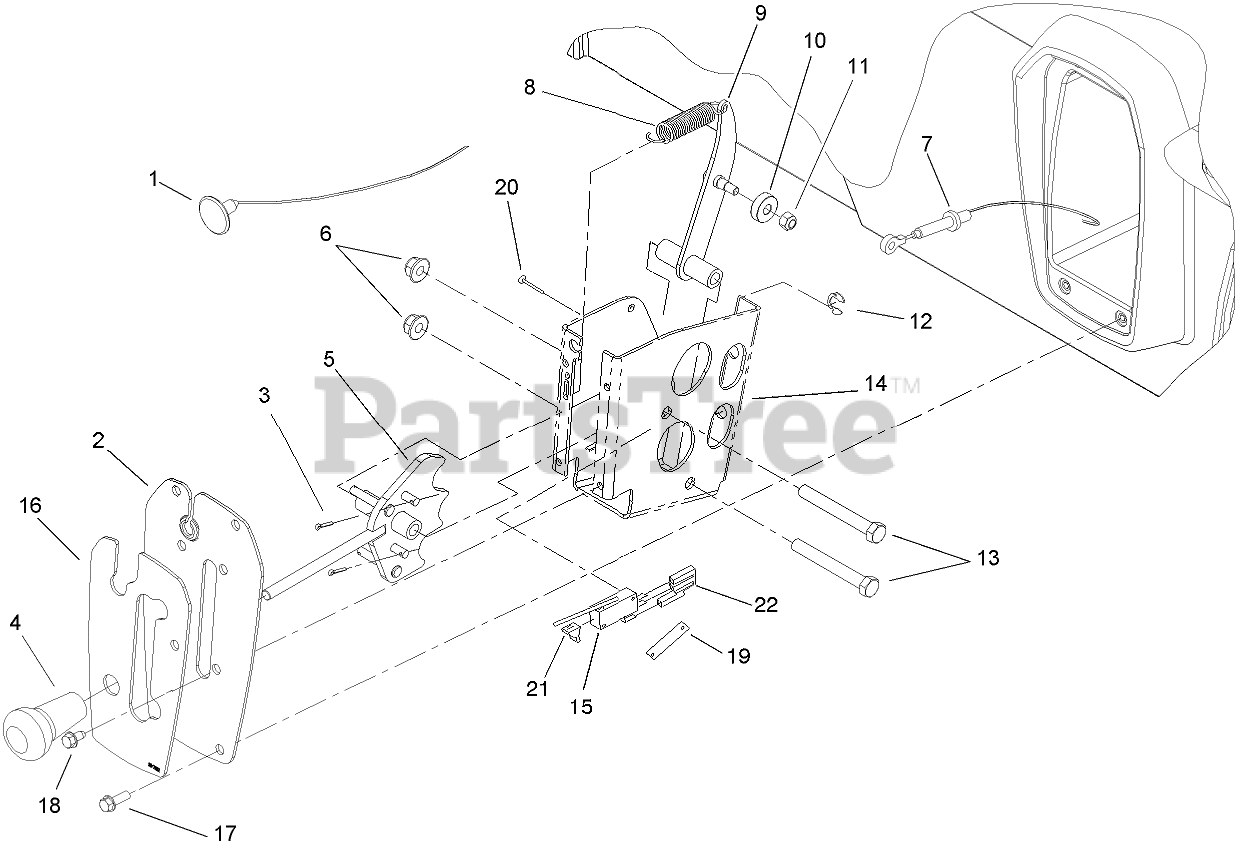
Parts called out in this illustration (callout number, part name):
1	CABLE-CHOKE
2	PLATE-SHIFTER
3	PIN-COTTER
4	KNOB-GRIP, SOFT
5	LEVER-SHIFT
6	NUT-HF, NI
7	Cable-Shift
8	SPRING-RETURN, PEDAL
9	ARM-DETENT
10	BEARING-BALL
11	NUT-LOCK, NI
13	SCREW-HH
14	BRACKET-SHIFT
15	SWITCH-MICRO
16	DECAL-SHIFTER
17	SCREW-HWH
18	SCREW
19	NUT-SPEED
20	SCREW-SPH
21	PLUNGER-SEAL
22	HARNESS-JUMPER, SHIFT
